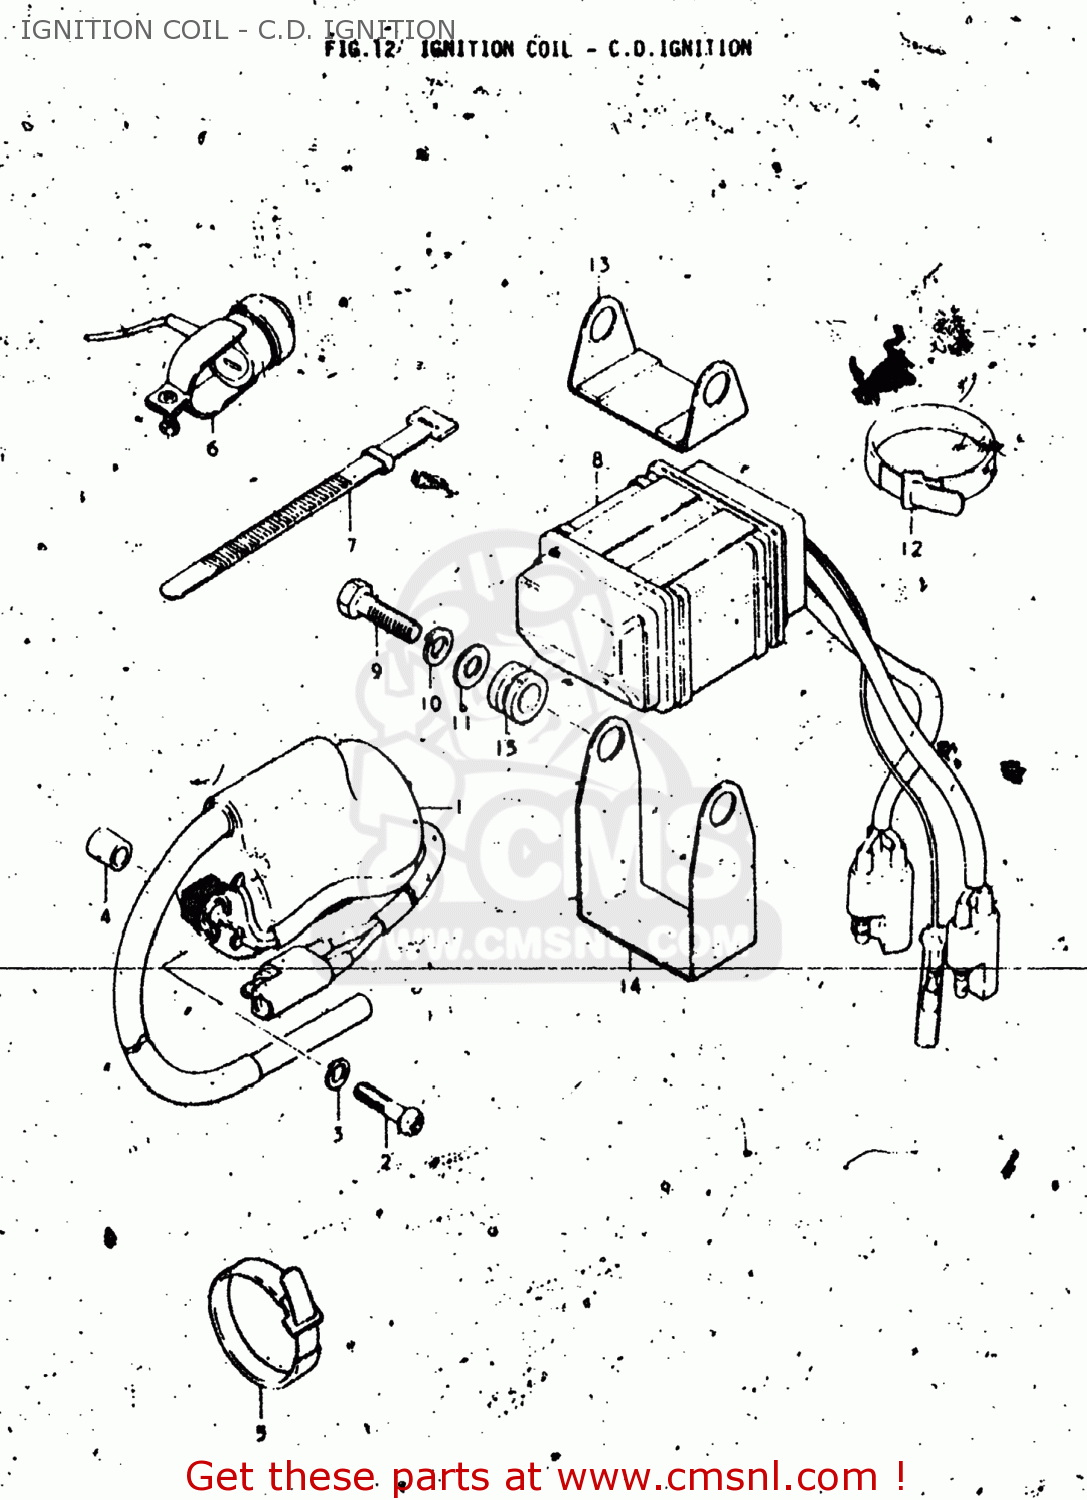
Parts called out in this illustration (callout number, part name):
1	COIL ASSEMBLY,IGNITION
2	SCREW
3	LOCK WASHER
4	SPACER
5	CLAMP
6	SWITCH ASSEMBLY
7	CLAMP(L:120)
9	BOLT
10	LOCK WASHER
11	WASHER
12	CLIP
15	CUSHION
